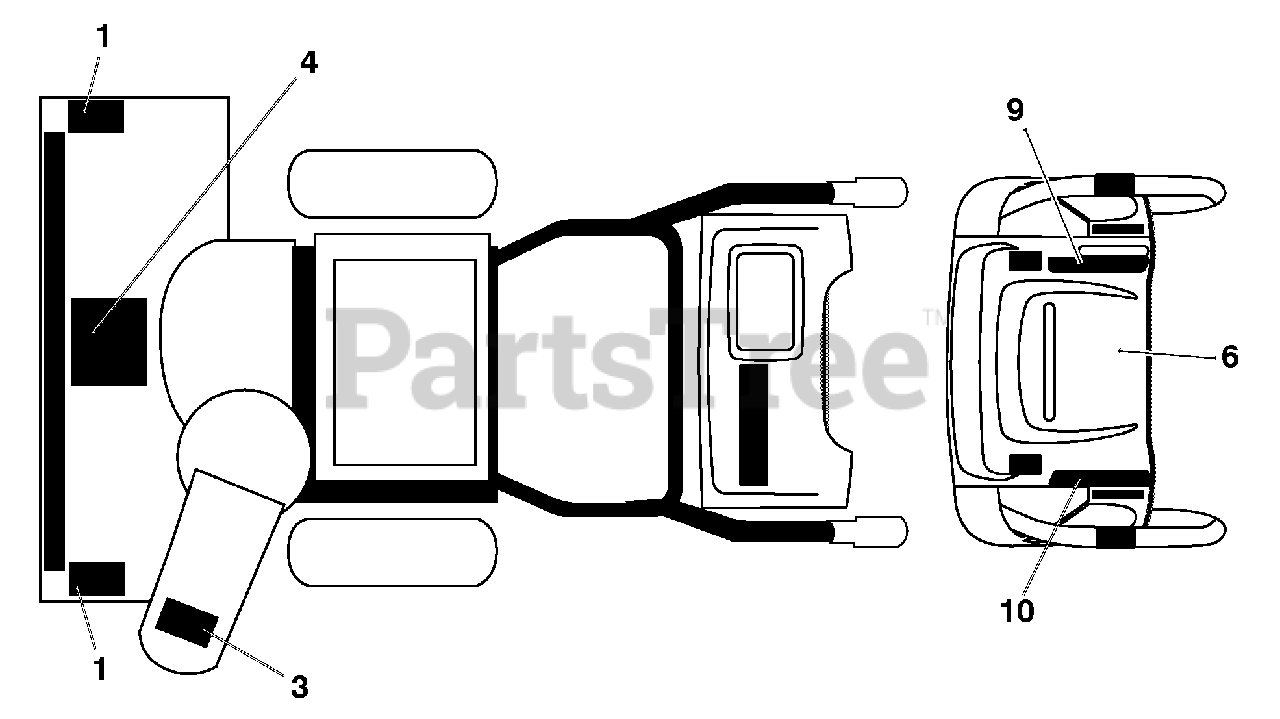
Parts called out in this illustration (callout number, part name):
1	DECAL, DANGER
3	DECAL, DANGER, DEFLECTOR
4	DECAL, DANGER
6	DECAL, INSTRUCTION
9	DECAL, SPEED CONTROL/TRIGGER
10	DECAL, REMOTE DEFLECTOR CONTROL/TRIGGER
10	OWNER'S MANUAL, ENGLISH
10	OWNER'S MANUAL, FRENCH
